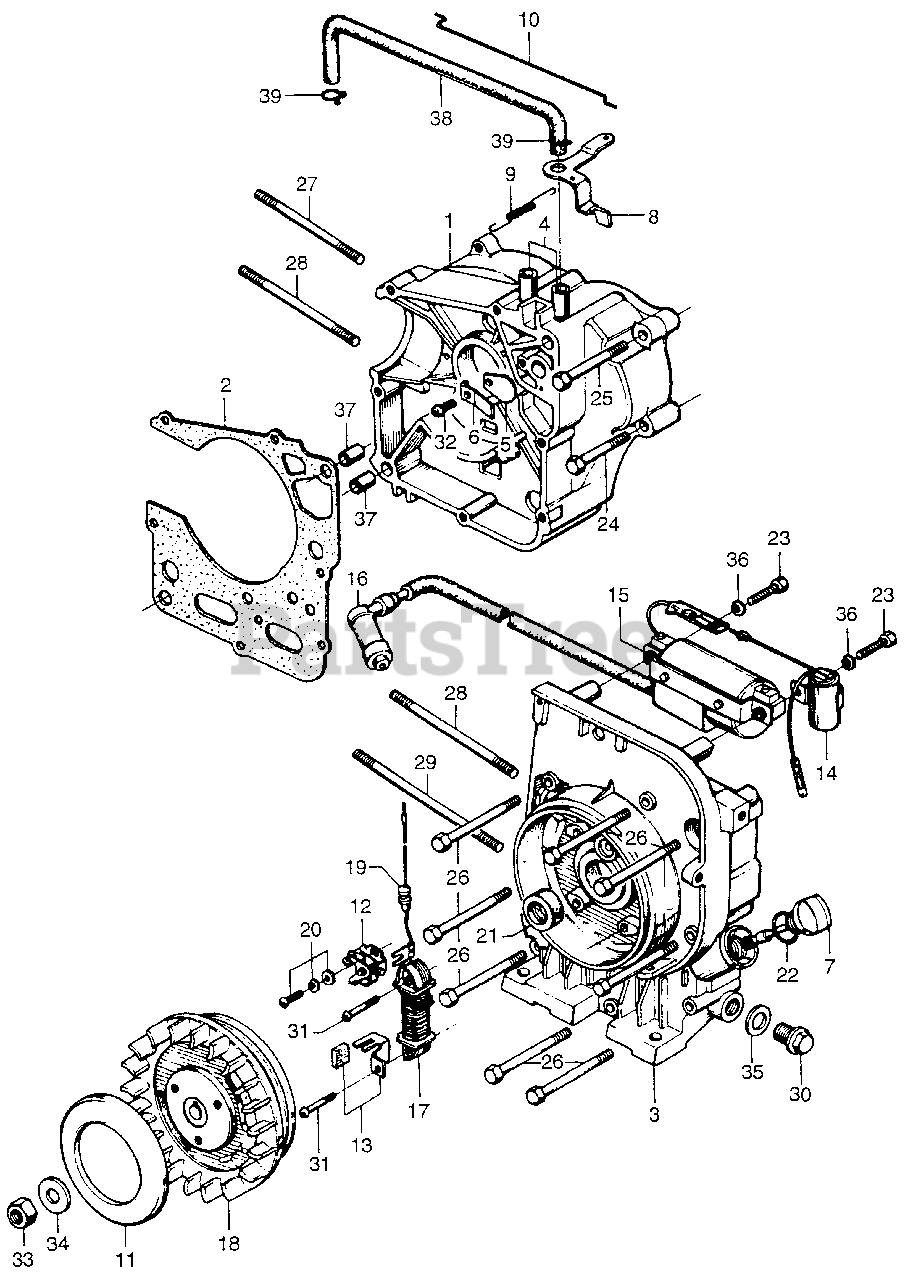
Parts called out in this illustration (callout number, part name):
1	CRANKCASE, R.
2	GASKET, CRANKCASE (NOT AVAILABLE)
3	CRANKCASE, L.
4	JOINT, BREATHER (NOT AVAILABLE)
5	VALVE, BREATHER
6	STOPPER, BREATHER
7	CAP, OIL FILLER (NOT AVAILABLE)
8	LEVER, CHOKE
9	SPRING, CHOKE LEVER (NOT AVAILABLE)
10	ROD, CHOKE (NOT AVAILABLE)
11	COVER, SEAL
13	FELT, OIL (DENSO)
15	COIL, IGNITION (NOT AVAILABLE)
15	COIL, IGNITION
16	TERMINAL ASSY., IGNITION
17	COIL, IGNITION (NOT AVAILABLE)
18	FLYWHEEL (NOT AVAILABLE)
19	GROMMET, WIRE
20	SCREW, STOP (NOT AVAILABLE)
21	OIL SEAL (15X25X6)
22	O-RING (16MM)
22	O-RING (15.8X2.4) (SHOWA)
23	BOLT, HEX. (5X25)
24	BOLT, HEX. (6X32)
25	BOLT, HEX. (6X45)
26	BOLT, HEX. (6X56)
26	BOLT, HEX. (6X56) (NOT AVAILABLE)
27	BOLT, STUD (6X80) (NOT AVAILABLE)
28	BOLT, STUD (6X90)
29	BOLT, STUD (6X115) (NOT AVAILABLE)
30	BOLT, DRAIN PLUG (12MM)
31	SCREW, PAN (4X20)
32	SCREW, PAN (5X8)
33	NUT, HEX. (10MM)
34	WASHER, PLAIN (10MM)
34	WASHER (10MM)
35	WASHER, DRAIN PLUG (12MM)
36	WASHER, SPRING (5MM)
37	PIN A, DOWEL (10X16)
38	TUBE (7X224)
38	TUBE (7X224) (NOT AVAILABLE)
38	BULK HOSE, FUEL (7.5X8000) (7.3X350)
39	CLIP, TUBE (C11)
39	CLIP, TUBE (B12)
